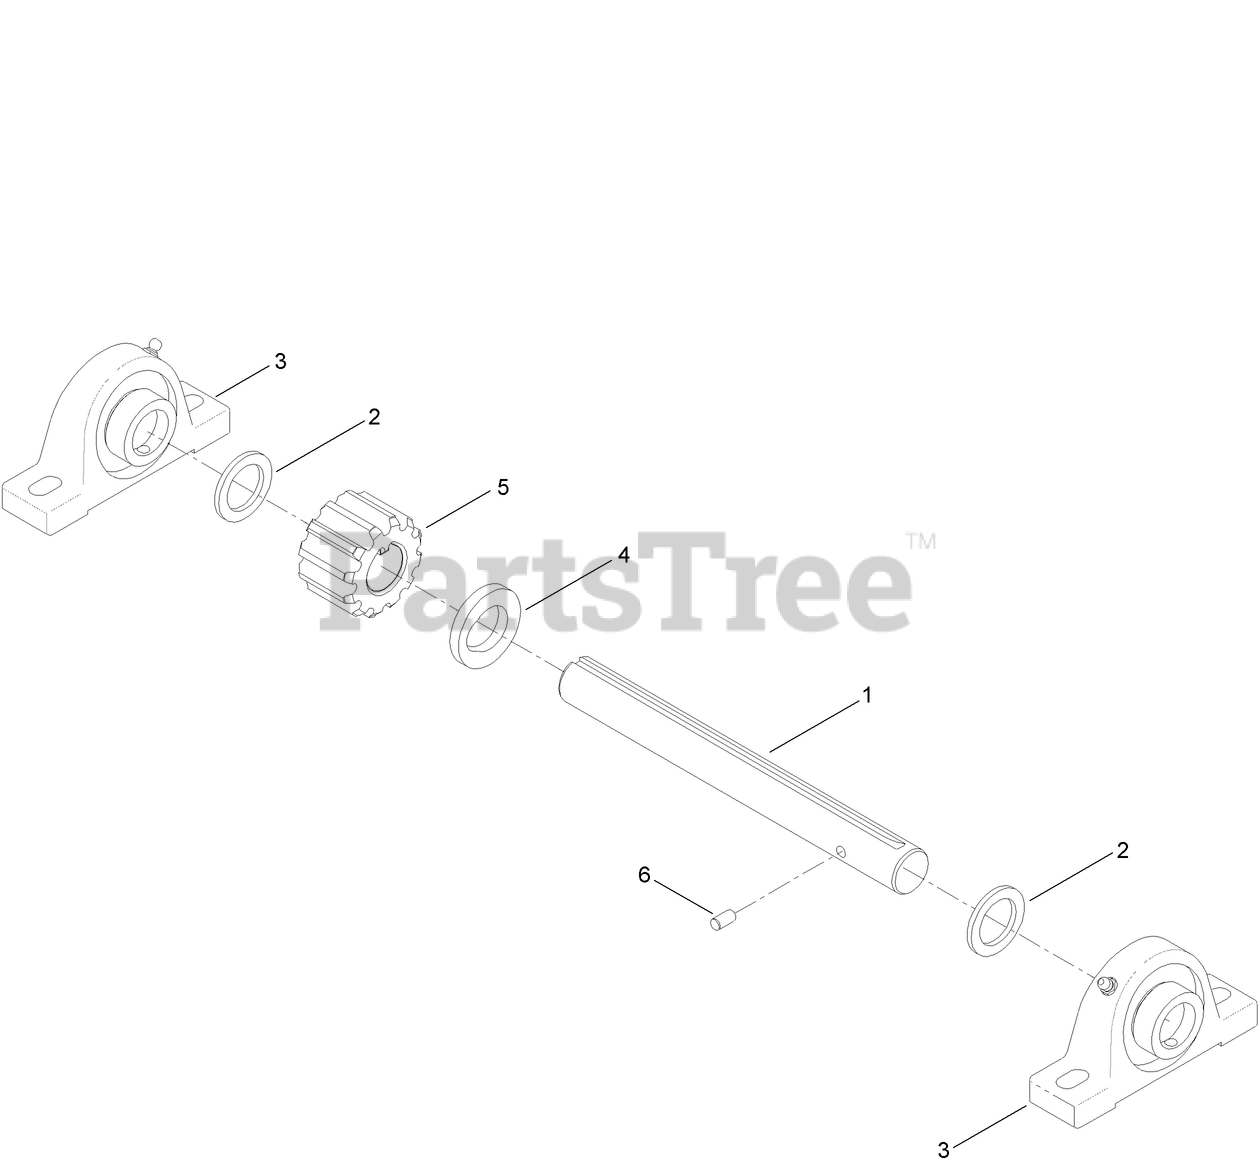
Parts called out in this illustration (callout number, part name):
1	SHAFT-PINION
2	WASHER-THRUST
3	BEARING-BLOCK, PILLOW
4	WASHER
5	GEAR-SPUR
6	PIN-DOWEL
